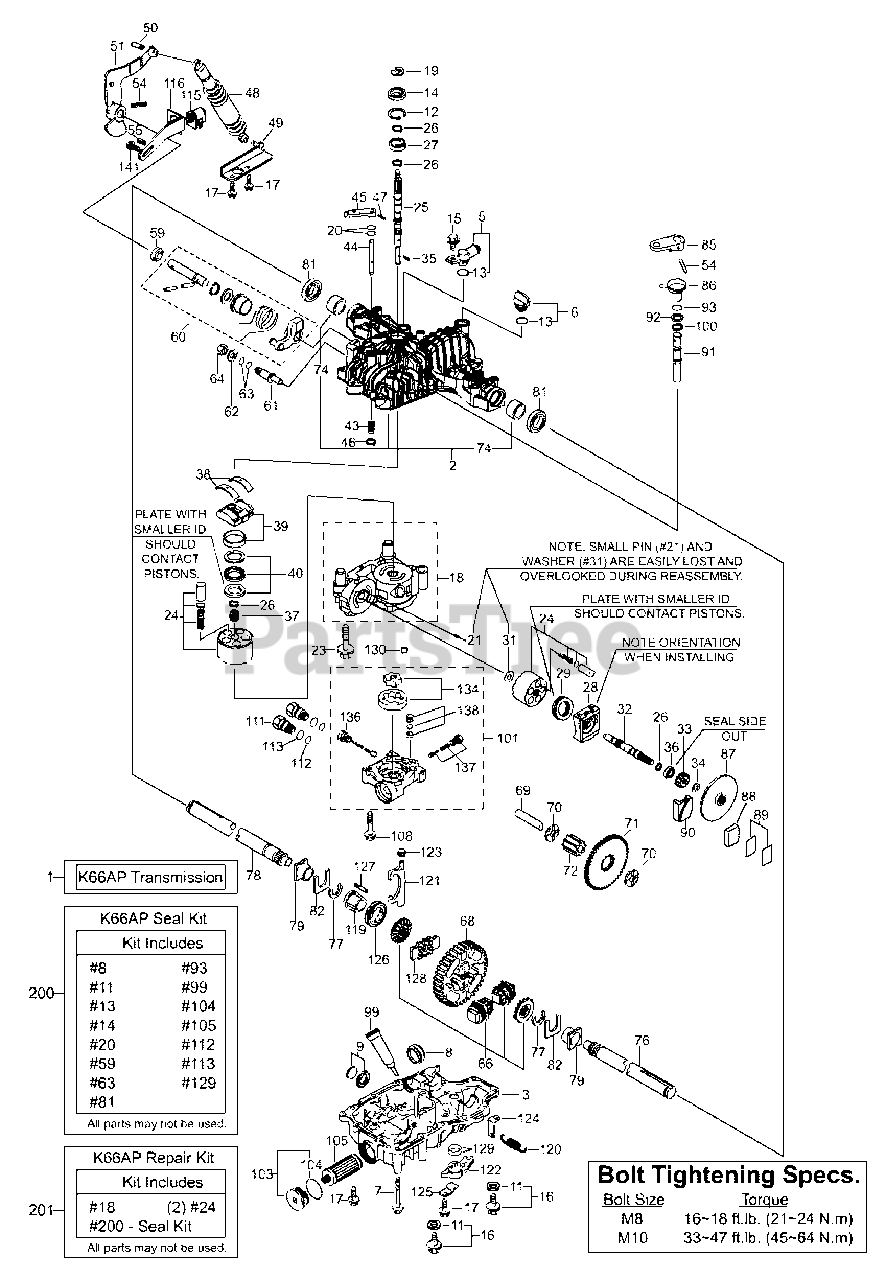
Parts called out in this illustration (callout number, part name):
1	TRANSMISSION, Tuff Torq, K66AP
2	* UPPER CASE KIT
3	* LOWER CASE
5	* FITTING KIT
6	* CAP KIT
11	WASHER SEAL 10
12	SNAP RING C 35
14	SEAL TC 153507
16	* DRAIN BOLT KIT
17	TAPPING SCREW 8 x 30
18	* CENTER CASE AB
19	E-RING
20	O-RING, 1A P10A
21	PIN 3 x 9.8
24	* CYLINDER BLOCK KIT
26	SNAP RING S15
27	BEARING 6202C3
28	MOTOR HOUSING
29	THRUST BEARING
31	WASHER 12 x 24 x 1
35	PIN 3 x 13.8
36	BEARING 6302DUC3
37	PUMP SPRING
38	THRUST METAL
39	SWASH PLATE ASSEMBLY
40	* THRUST BEARING KIT
44	BYPASS SHAFT
45	BYPASS LEVER
47	SPRING PIN 3.0A x 20
48	* SHOCK ABSORBER
51	* CONTROL LEVER
54	ROLL PIN 6 x 40
59	SEAL TC 162606
60	* CONTROL SHAFT KIT
63	O-RING 1A P14
66	* DIFFERENTIAL GEAR KIT
68	* FINAL GEAR
69	FINAL PINION SHAFT
70	WASHER 15 x 35 x 3.2
71	REDUCTION GEAR (53T)
72	FINAL PINION Gear (11T)
74	BUSHING 25.4
76	AXLE SHAFT, LEFT
77	RETAINING RING 23
78	AXLE SHAFT, RIGHT
79	BUSHING 25.4
81	SEAL S 25.4 x 42 x 8
82	THRUST WASHER
85	* BRAKE LEVER
86	* BRAKE RETURN SPRING
90	BRAKE ACTUATOR
91	BRAKE SHAFT
92	WASHER 16 x 23 x 1.6
93	O-RING 1A P12
99	* SEALANT
101	* PUMP CASE KIT (K664C & E)
103	* CAP KIT
115	* SWITCH 6440-11 DELTA
116	* SWITCH PLATE
120	DIFFERENTIAL RETURN SPRING
121	DIFFERENTIAL LOCK FORK
122	DIFFERENTIAL LOCK LEVER
123	* LEVER PIVOT
124	SPRING HOOK
126	DIFFERENTIAL LOCK SLIDER
127	* DIFF LOCK PIN
128	* DIFF LOCK PLATE
129	0-RING 1A G25
134	* ROTOR SET
136	CHARGE RELIEF VALVE
137	IMPLEMENT RELIEF VALVE
138	3RD CHECK VALVE
141	TAPPING SCREW 8 x 20
200	* KIT, Seal
201	* REPAIR KIT
